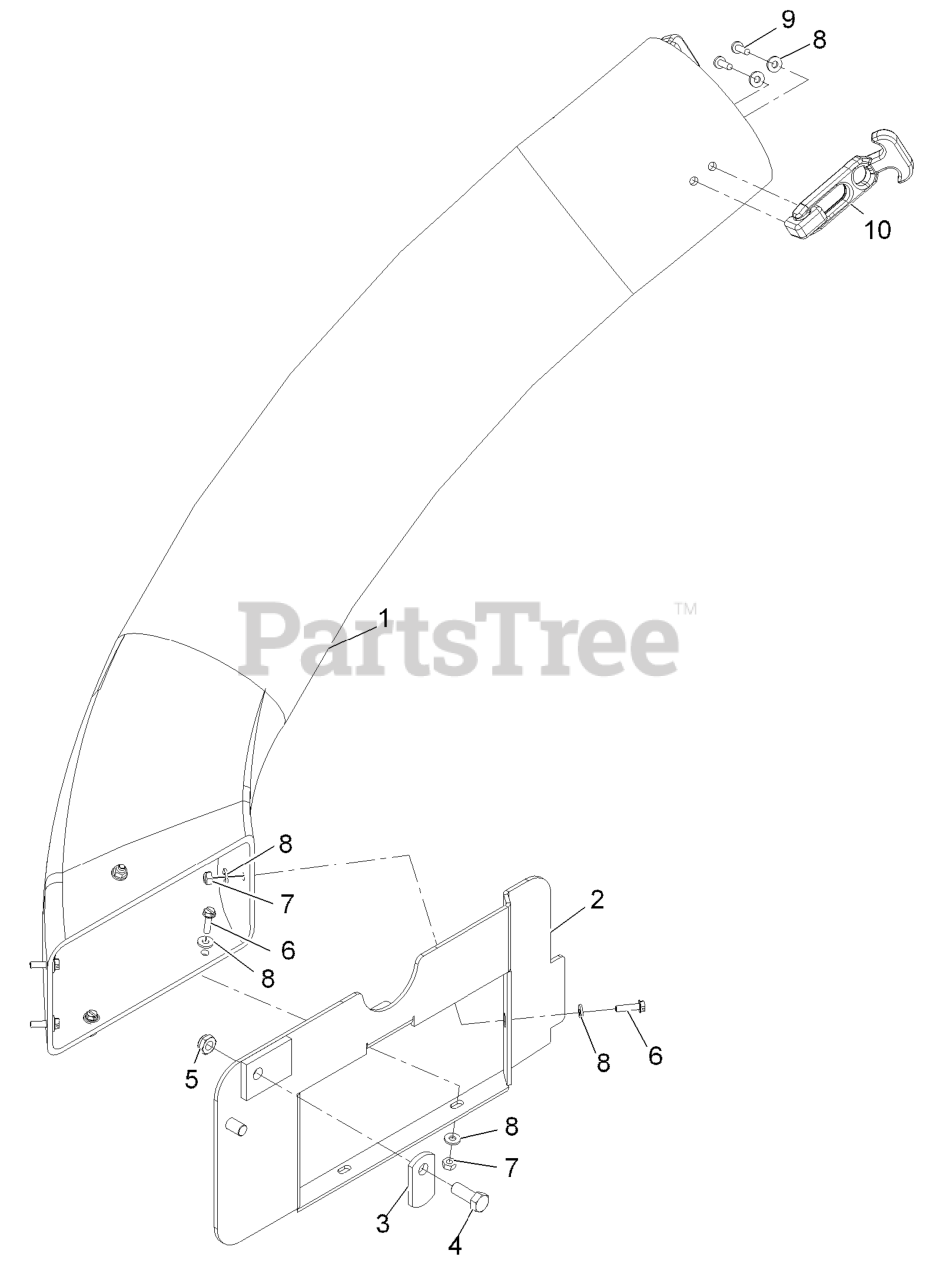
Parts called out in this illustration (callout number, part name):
1	BOOT-LOWER
2	BOOT FRAME ASM
3	LATCH-CATCHER, GRASS
4	SCREW-HH
6	SCREW-HWH
7	NUT-LOCK, NI
8	WASHER-FLAT
9	SCREW-PPH
10	LATCH-RUBBER
